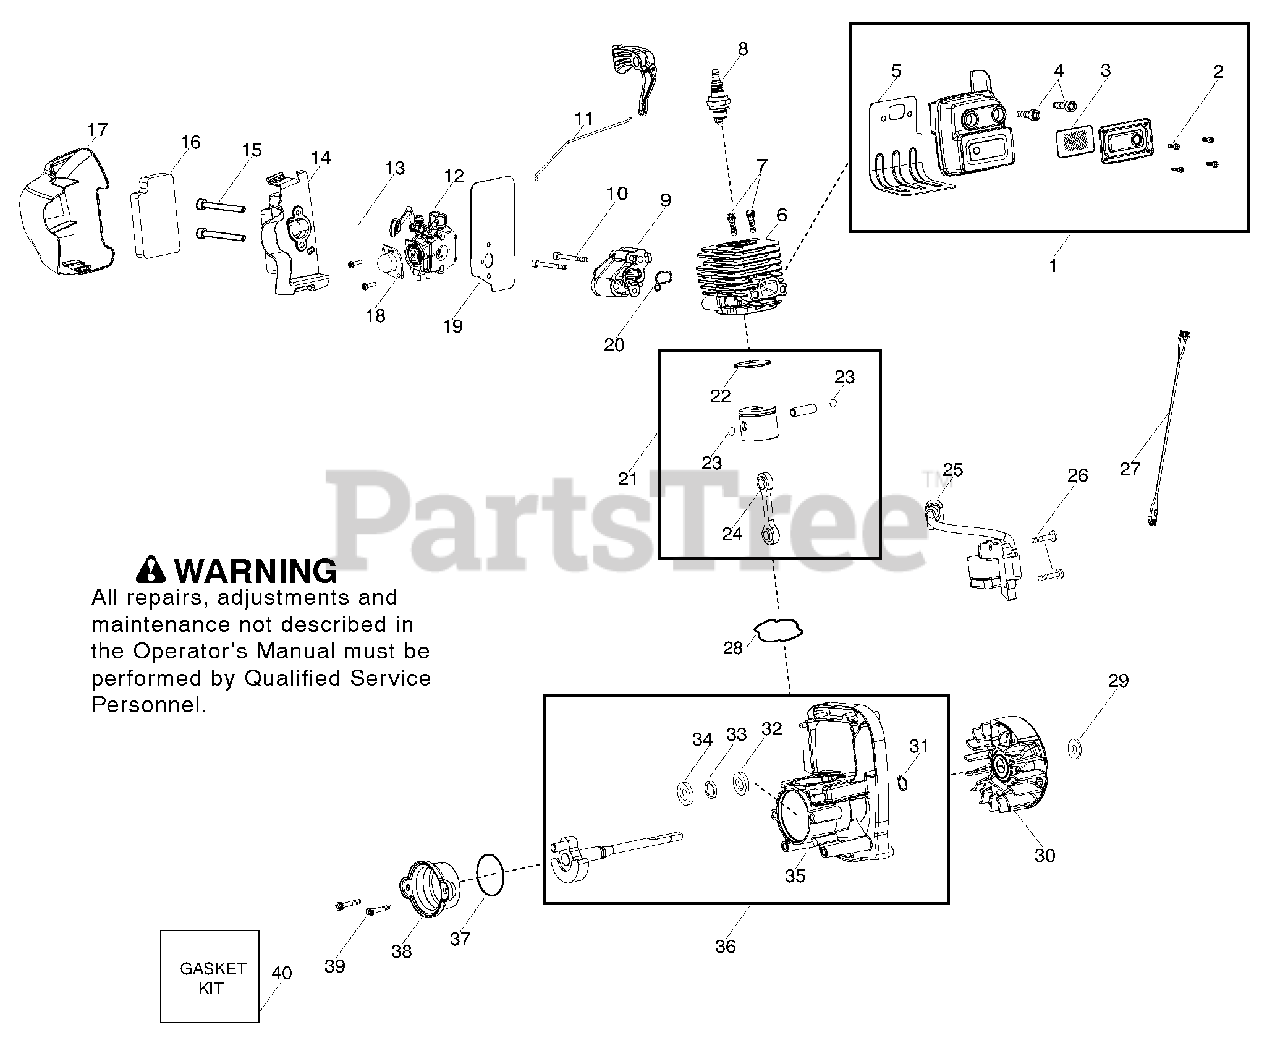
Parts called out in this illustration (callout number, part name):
1	Assy - Muffler
2	Screw
3	Kit - Spark Screen
5	Gasket-Muffler (gasket kit)
8	Spark Plug (RCJ-6Y)
9	Adapter - Carb.
11	Linkage - Throttle
12	Kit - Carb. Assy (WT847)
13	Lever- Choke (Gold)
14	Base - Airbox
17	Cover - Air Box Filter
18	Bulb - Purge (walbro 188-16)
19	Gasket (Carb / Adapter) (gasket kit)
20	O-Ring (Adapter / Cylinder) (gasket kit)
21	Kit - Piston / Connecting Rod
22	Ring - Piston
23	Retainer - Wrist Pin
24	Kit - Assy. Connecting Rod
25	Module - Ignition
27	Assy - Wire Harness
28	O-Ring (Cyl/Crankcase) (gasket kit)
30	Assy - Flywheel
31	Retainer - Crankshaft
32	Bearing - Outer
34	Bearing - Inner
35	Assy - Crankcase
36	Assy - Crankcase & Crankshaft
37	O-Ring (Rear Plug) (gasket kit)
38	Assy - Rear Plug
40	Kit - Gasket
